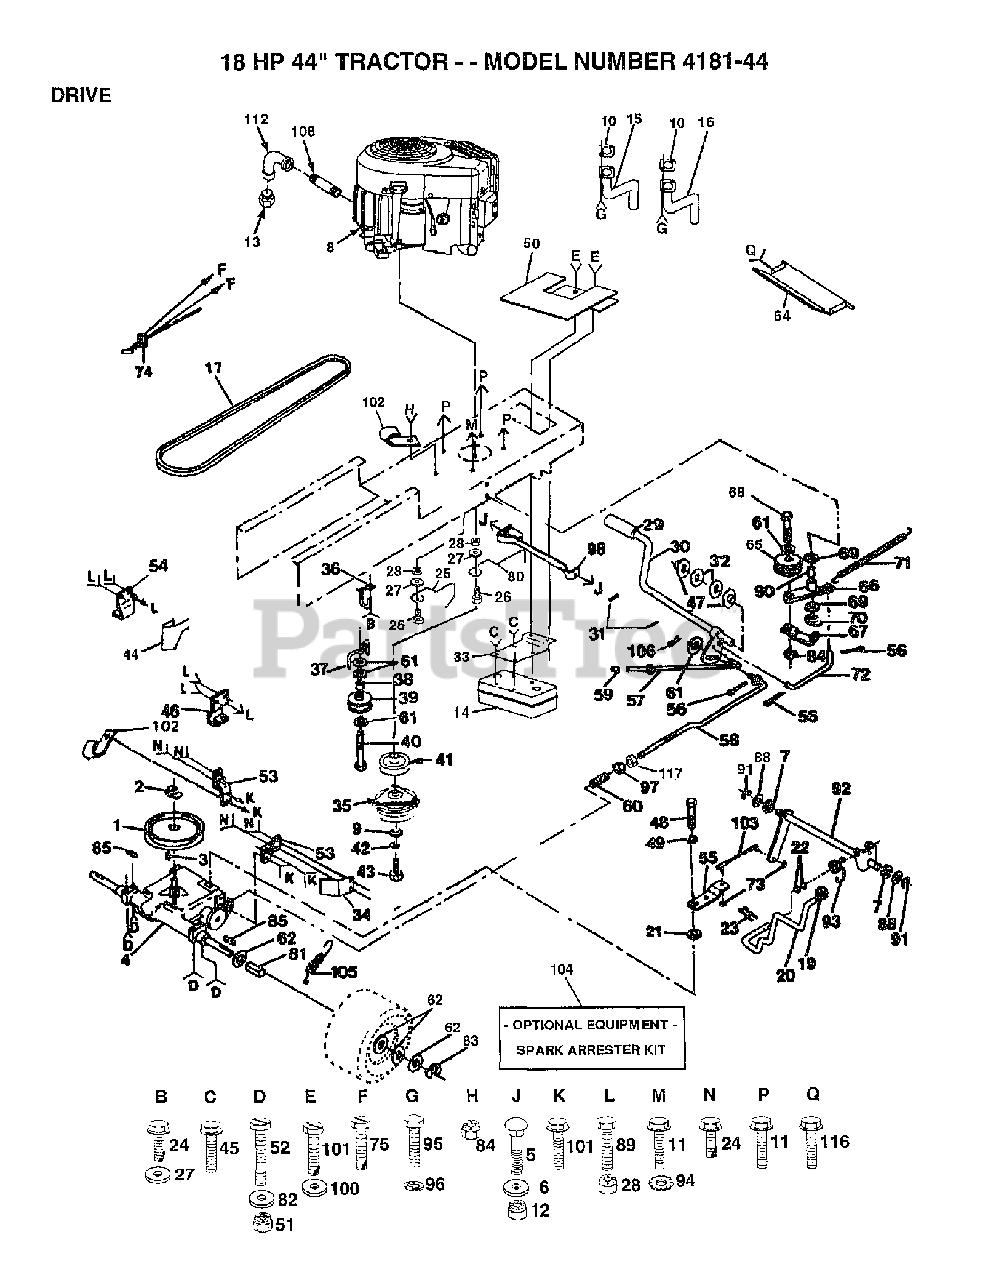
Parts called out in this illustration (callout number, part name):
1	PULLEY TRANSAXLE
3	KEY.WOODRUFF
5	BOLT
6	WASHER T
7	BUSHING.STEERING.ROD
8	Poulan TBD
10	Poulan TBD
12	LOCKNUT
15	EXHAUST ASM. LEFT
16	EXHAUST ASM. RIGHT
17	BELT.GROUND.DRIVE
19	KNOB T (1/2-HOLE)
20	ROD SHIFTER
21	WASH-SHFT PLT LT
22	WASHER
23	PIN COTTER
26	BOLT
27	WASHER
28	LOCKNUT
29	PEDAL COVER
31	Drive Pin, 3/16 X 1"
32	WASHER LT
34	KEEPER,BELT RH
37	BELT KEEPER LT
38	SPACER T
39	FLAT IDLER PULLEY
41	ENGINE PULLEY
42	LOCKWASHER
43	BOLT
44	KEEPER BELT LH
45	SCREW ST
46	BRKT TRANS RH
47	BEARING.NYLON
49	WASHER PM
50	HEAT SHIELD
51	NUT.71038.31-18.HEX.NYLOCK
52	BOLT HEX
53	STRAP TORQUE
54	BRKT TRANS LH
55	ARM,SHIFT
56	COTTER PIN
57	BRAKE PARK ROD
58	ROD BRAKE
59	PLUNGER CAP
60	SPRING,ROD BRAKE
65	Idler Pulley
67	RETAIN BELT
68	Hex Bolt
69	WASHER LT
70	KLIP RING
71	SPRING, RETURN LT
73	NUT 1/4-28
74	THROTTLE CONTROL
80	KEEPER,BLT ENG LT
81	SPACER HYT
82	WASHER M
83	E RING HYT
84	NUT
88	WASHER D
90	BEARING LT (2 2)
91	KLIP RING
92	SHAFT,SHIFTER
93	SPRING,TORSION
94	LOCKWASHER
96	LOCKWASHER
97	NUT
98	BRACKET ASM MTG
100	WASHER
101	Screw, Lt
102	CLIP T
104	KIT.SPARK ARRESTOR(392390 B&S)
105	SPRING T
106	RETAINER M
108	NIPPLE, PIPE 3/8NPT X 4-1/2
112	ELBOW
117	NUT
